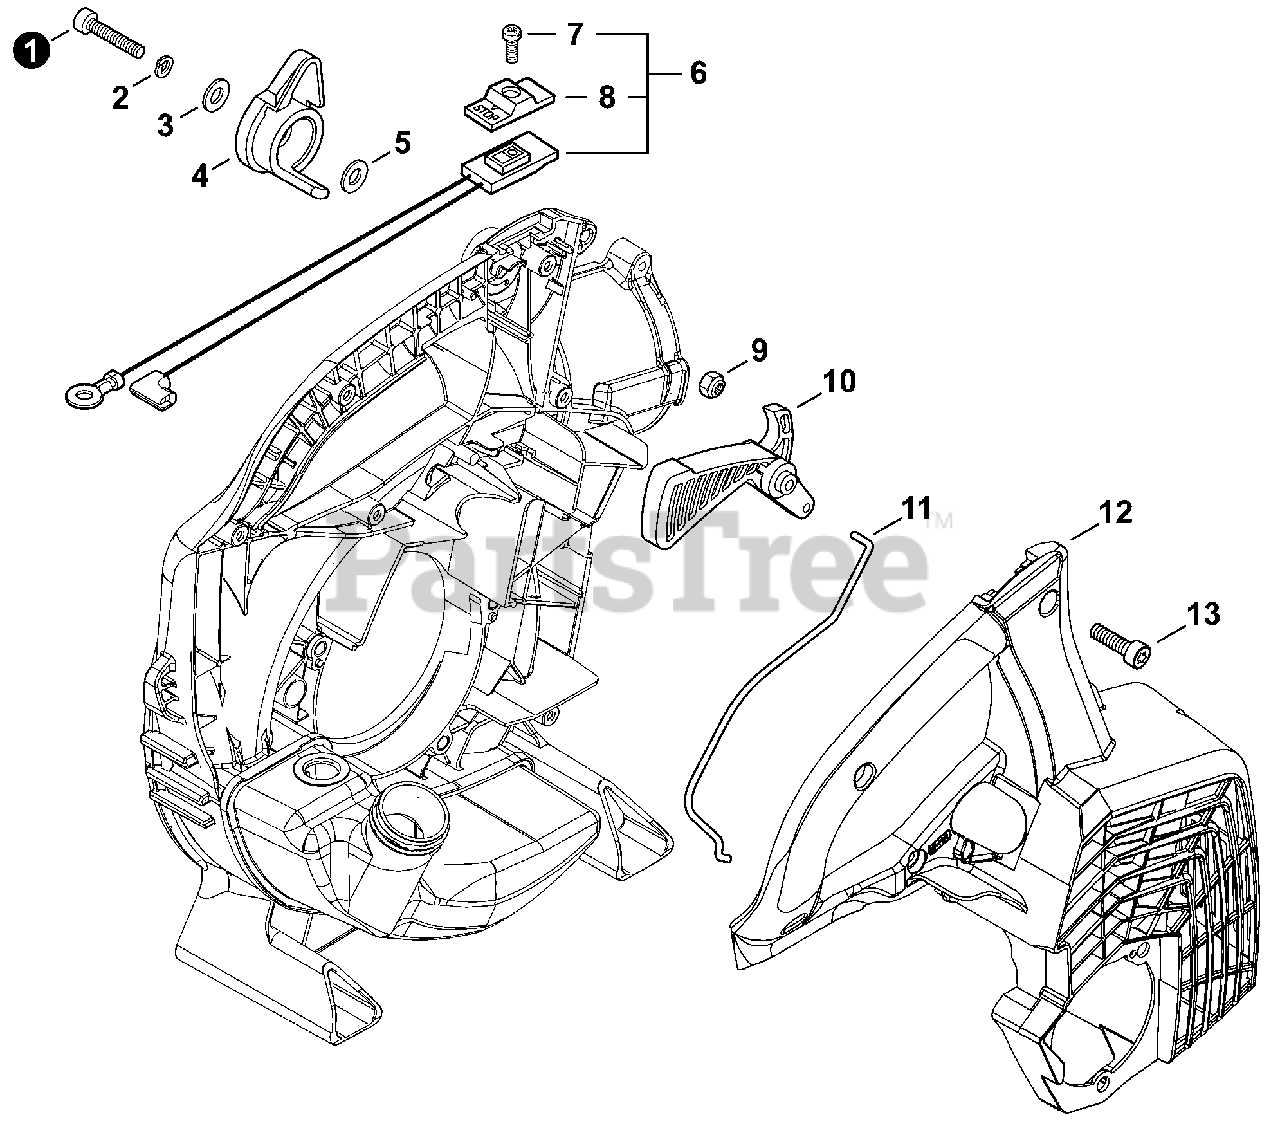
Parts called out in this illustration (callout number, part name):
1	BOLT, TORX 5×25
2	WASHER, SPRING 5
3	WASHER 5.5×12×0.8
4	CONTROL, THROTTLE
5	WASHER 5.5×12×0.8
6	SWITCH, ON-OFF
7	SCREW 3×10
8	KNOB, SWITCH
9	NUT, LOCK M5
10	TRIGGER, THROTTLE
11	ROD, THROTTLE
12	COVER, ENGINE
13	BOLT, TORX 5×20
